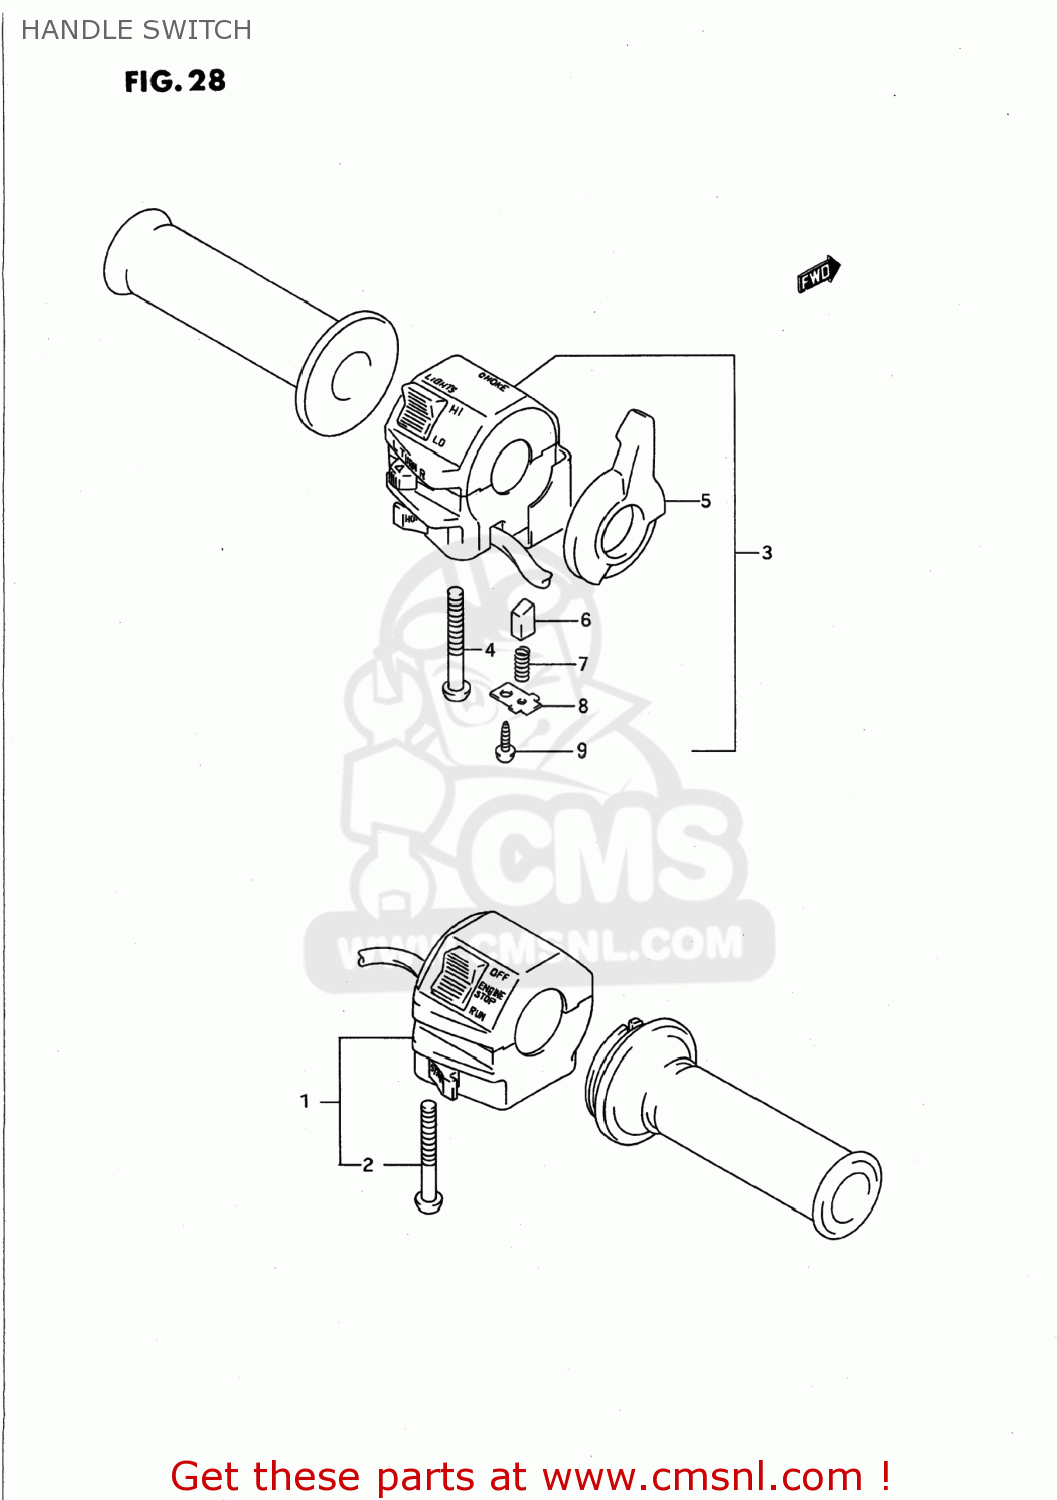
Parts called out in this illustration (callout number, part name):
1	SWITCH ASSEMBLY,HANDLE,RIGHT
2	SCREW, 5X45
3	SWITCH ASSEMBLY,HANDLE,LEFT
4	SCREW, 5X45
5	LEVER,CHOKE
6	PIECE,SLIDE
7	SPRING
8	PLATE
9	SCREW
